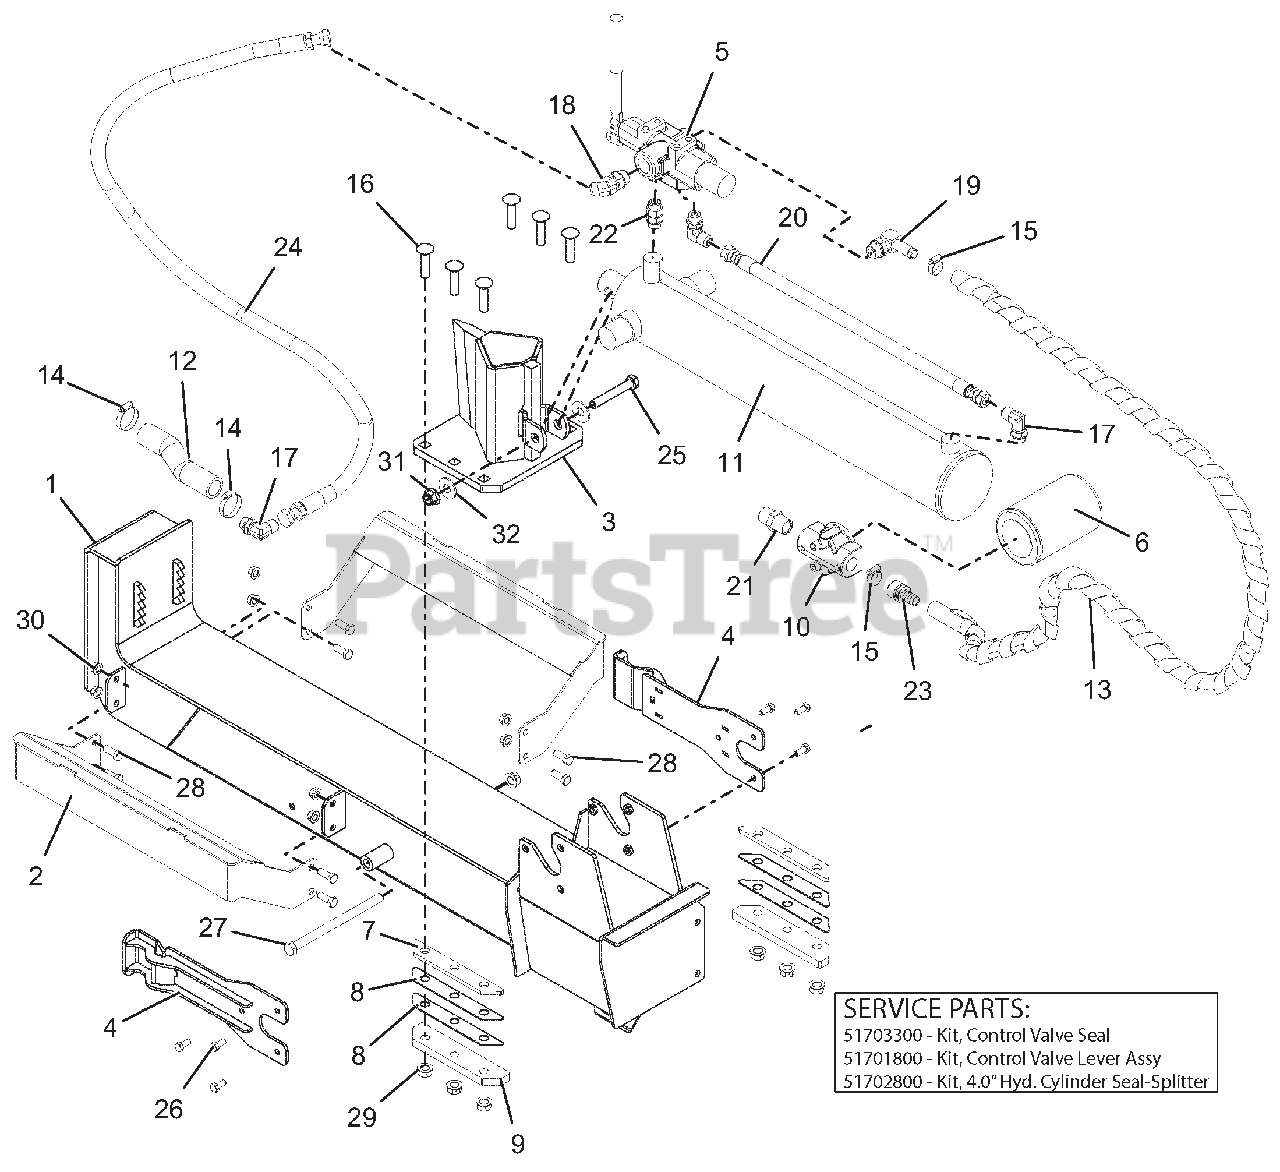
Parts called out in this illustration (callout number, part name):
1	WLDMT, BEAM - 22 TON SPLITTER
2	WLDMT, CRADLE, LOG SPLITTER
3	WMT, WEDGE - SPLITTER
4	WLDMT, PLATE - STRIPPER
5	VALVE CONTROL-SPLITTER
5	KIT,CONTROL VALVE SEAL
5	KIT,CONTROL VALVE LEVER ASSY
6	FILTER,OIL-W/BYPASS
7	SPACER, WEDGE
8	SHIM,SPLITTER WEDGE
9	RETAINER,WEDGE
10	HEAD,FILTER-3/4 NPT BYPASS
11	CYLINDER, SPLITTER 4.0
11	KIT,4.0" HYD CYL SEAL-SPLITTER
12	HOSE, HYD - SUCTION 7.375"
13	HOSE, HYD-RET 801-10 WP 74"
14	CLAMP-HOSE 1.50X.81X1.42
15	CLAMP,.88 DIA. HOSE
16	BLT-RDHDSQNKFTH.50-13X2 G8YWZC
17	FTG,HYD 6801-8-8
18	FTG,HYD 6802-8-10
19	FTG,HYD 4601-10-10
20	HOSE, HYD - 22"
21	FTG,HYD 5404-12-12
22	FTG, HYD - STR 08MAORB-08MORB
23	FTG,HYD STRAIGHT 10-12
24	HOSE, HYD - 58"
25	@BLT-HEX .50-13X3.25 GR5 YWZC
26	@BLT-HEX .31-18X.75 GR5 YWZC
27	@BLT-HEX .50-13X7.50 GR5 YWZC
28	@BLT-HEX .38-16X1.00 GR5 YWZC
29	NUT-LK-CTR-FLG .50-13 YWZC
30	@NUT-LK-TOP-FLG .38-16 YWZC
31	@NUT-LK-NYL-FLG .50-13 YWZC
32	@WSHR-FL-STL.563X1.38X.109YWZC
